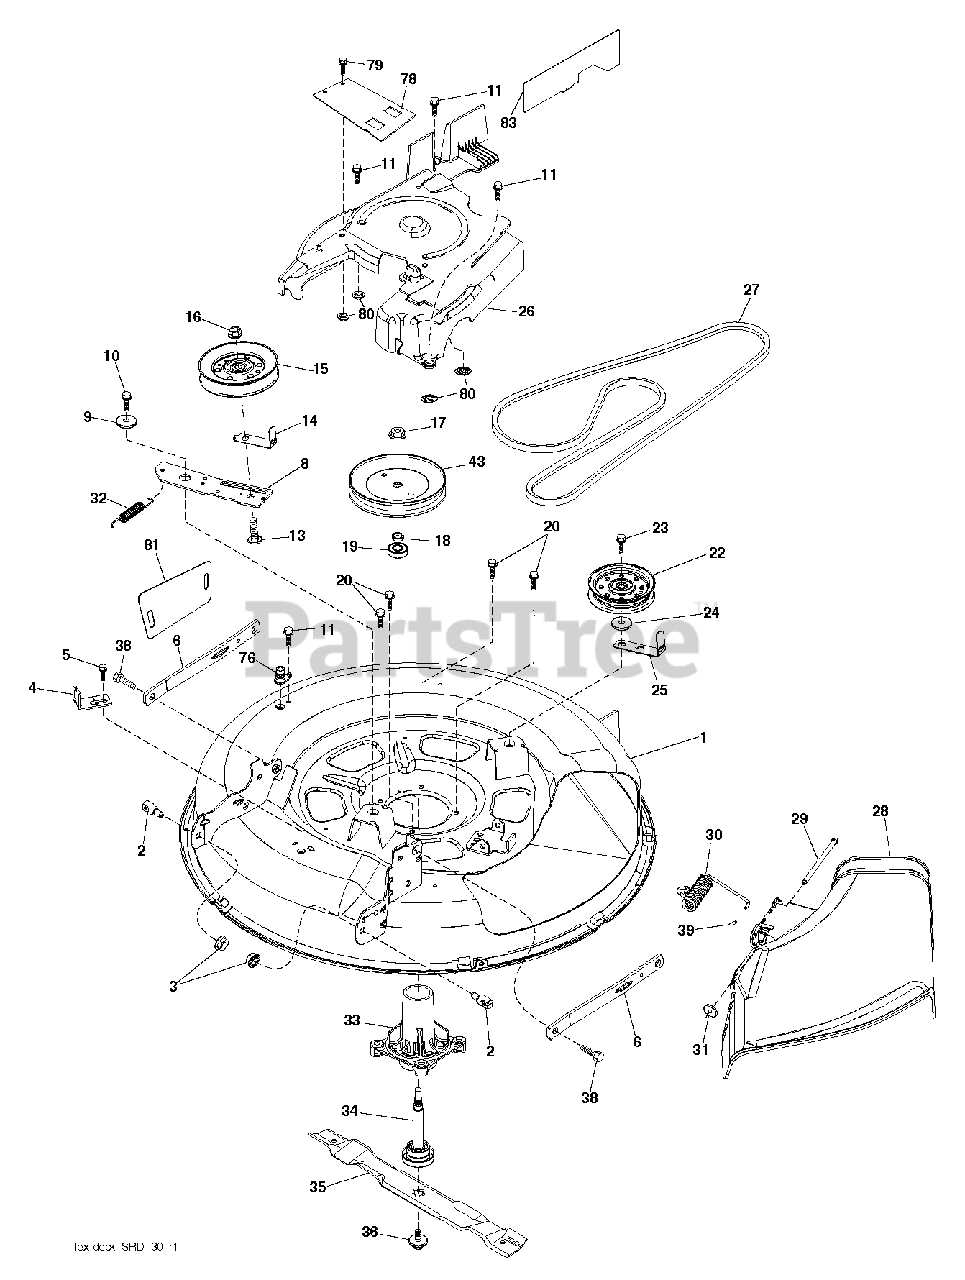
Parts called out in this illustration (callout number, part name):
1	DECK.WELDMENT.PNT.30"SRD
2	STUD.FASTNER.W/ANTI-ROTATE
3	NUT LOCK HEX FLANGE 5/16-18
4	BRACKET.CLUTCH.CABLE
5	BOLT.5/16HEX.WHS.HD
6	ARMS.SUSP.MOWER.REAR.SRD
8	ARM.IDLER.30"SRD
9	SPACER.RETAINER
10	SCREW 3/8-16X1
11	SCREW.1/4-20X5/8
13	BOLT.3/8-16X1.50
14	KEEPER, BELT IDLER
15	PULLEY.IDLER.4.25
16	NUT LOCK FLG 3/8-16 UNC
17	NUT.FLANGE.LOCK.TOP
18	WASHER.SPACER.MANDREL
20	SCREW, WASHER HEAD
22	PULLEY.IDLER.FLAT.46.PR.DR.
23	SCREW LT
24	WASHER
25	KEEPER.BELT.30"SRD
26	COVER.ASM.MANDREL.30"
27	V-BELT.DRIVE.MOWER.30"
28	SHIELD.DEFLECT.MWR.30S.BLACK
29	PIN.HINGE.30".SRD
30	SPRING.TORSION.DEFLECT
31	NUT PUSH M
32	SPRING.MOWER.DRIVE.ELECTRIC
33	HOUSING.MANDREL.4PT.
34	SHAFT.ASM.MDRL.N/GREASE.38
35	BLADE, MULCH.LRV30
36	BOLT.WASHER.ASM.7/16-2
38	BOLT.SHOULDER
39	CAP-SLEEVE LT
43	PULLEY, MANDREL 6.5 PD
76	PORT.WASHOUT
78	GUARD ARM CLUTCH
79	SCREW.HI-LO.CONSOLE
80	PALNUT 1/4
81	SHIELD SUSPENSION
